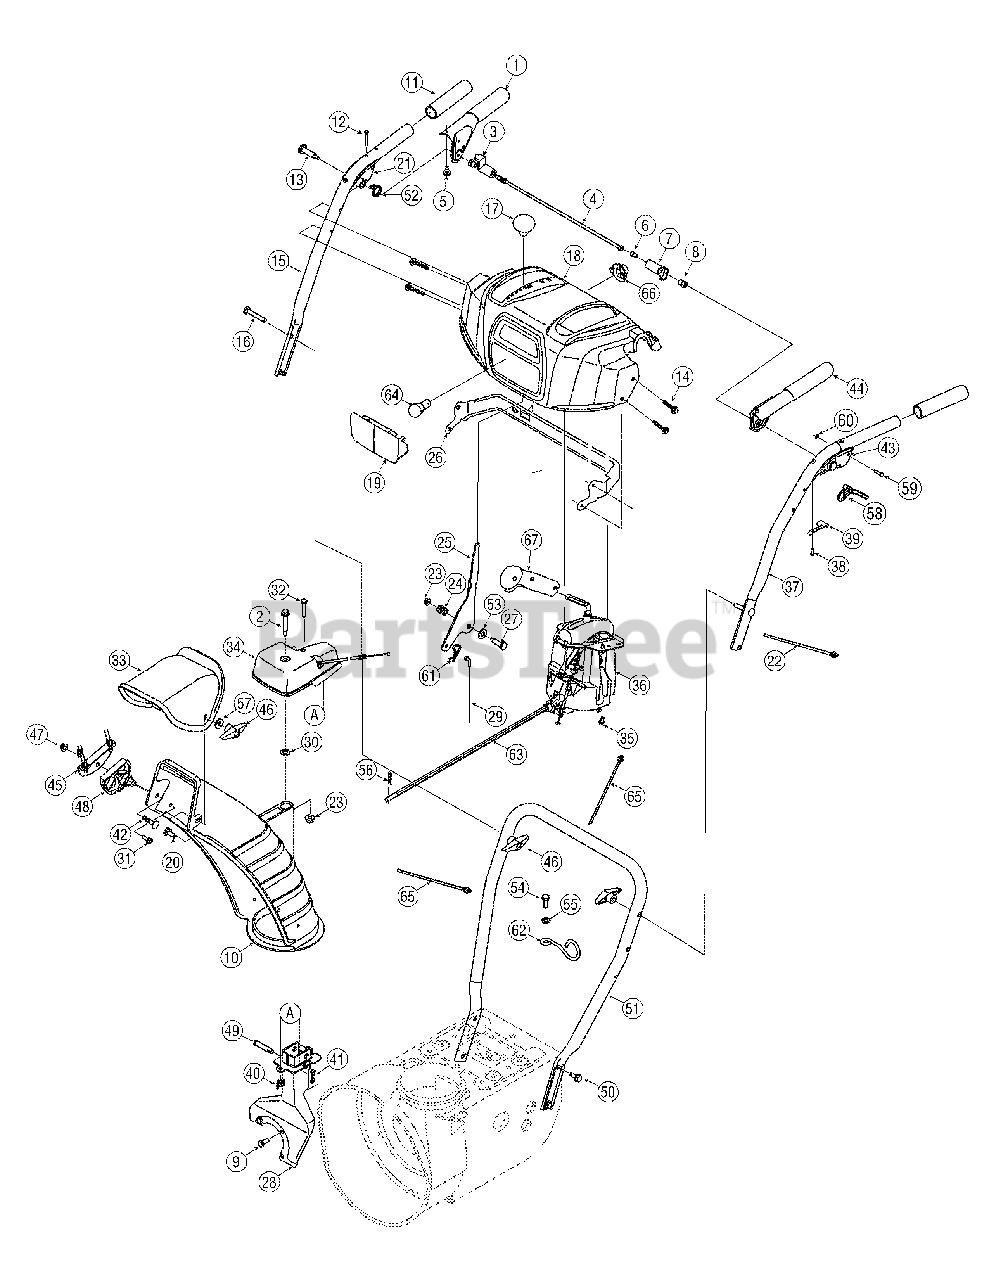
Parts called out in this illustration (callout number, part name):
1	Handle Engagement Assembly RH
2	Flange Shoulder Screw
3	Lock Plate
4	Pivot Rod
5	Rubber Bumper
6	Screw, 1/4-20 x .500
7	Clutch Lock Cam
8	Shoulder Nut, 1/4-20
9	Hex Screw, 5/16-24 x .750
10	Lower Chute
11	Handle Grip
12	Screw, #10-24 x 0.375
13	Shoulder Screw, 1/4-20
14	Screw, 1/4-20 x 1.625
15	Upper Handle RH
16	Carriage Screw, 5/16-18 x 2.25
17	Shift Knob
18	Handle Panel
20	Carriage Bolt, 5/16-18 x 1.0
21	Handle Clutch Lock RH Assy
22	Cable Tie
23	Flange Lock Nut, 1/4-20
24	Compression Spring
25	Shift Lever
26	Panel Bracket
27	Shoulder Screw
28	Chute Support Bracket
29	Speed Selector Cable
30	Flat Washer, .25 x .630 x .0515
31	Hi-Lo Screw, 1/4-15 x .75
32	Hex Screw, 1/4-20 x 3.00
33	Upper Chute
34	4-Way Chute Gearbox Assembly
35	Hi-Lo Screw, 1/4-15 x 0.5
36	4-Way Chute Control™ Assembly
37	Upper Handle LH
38	Screw, #8-16 x 0.50
39	Clutch Lock Spring
40	Wing Nut, 1/4-20
41	Bow Tie Cotter Pin
42	Carriage Bolt, 5/16-18 x 1.50
43	Handle Clutch Lock LH Assy
44	Handle Engagement Assembly LH
45	Cable Bracket
46	Wing Knob
47	Flange Lock Nut, 5/16-18
48	Chute Tilt Cable Guide
49	Clevis Pin
50	Screw, 5/16-18 x 0.75
51	Lower Handle
52	Torsion Spring
53	Flat Washer
54	Screw, M8-1.25
55	Flat Washer, .330 x .630 x .0635
56	Cotter Pin
57	Flat Washer, .349 x .879 x .063
58	Steering Control
59	Pin, 3/16
60	E-Ring
61	Click Pin
62	Cable Guide
63	Chute Rod
65	Cable Tie
66	Light Socket
67	Handle Assembly
